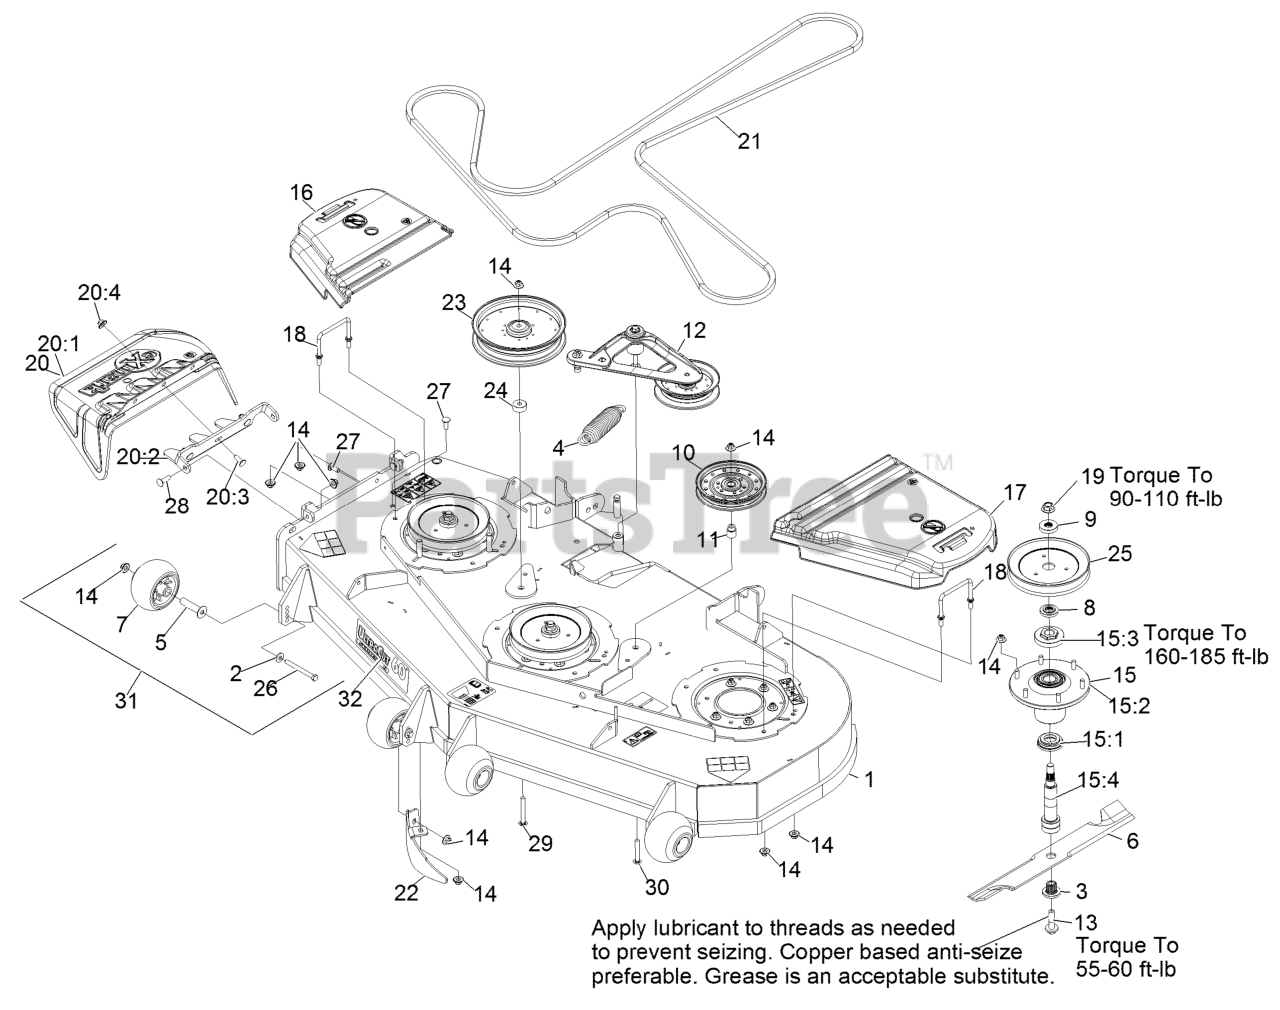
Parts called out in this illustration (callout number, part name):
1	DECK ASM,W/DECALS 60
2	WASHER-BELLEVILLE
3	BUSHING,SPLINED
4	SPRING-EXTENSION
5	AXLE, ROLLER
6	Blade-Extreme 2, 20.50"
7	ROLLER-SCALP, ANTI
8	SPACER,SPLINED STEPPED
9	SPACER,SPLINED
11	BUSHING-IDLER
12	DECK IDLER ASM
13	SCREW,SEMS 1/2-20 X 2.19
14	Nut-Nyloc 3/8-16 Flg
15	ASM,SPINDLE HOUSING
15:1	GUARD,BOTTOM
15:2	ASM,CUTTER HOUSING
15:3	NUT, SPINDLE 7/8-14
15:4	SPINDLE,DOUBLE SPLINE
16	COVER-BELT, RH
17	COVER-BELT, LH
18	WIREFORM-COVER
19	NUT-FLANGE, CENTERLOCK
20	ASM,DISCHARGE CHUTE
20:1	CHUTE,DISCHARGE
20:2	BRACKET,DISCHARGE CHUTE
20:3	SCREW-CARR
20:4	Nut-Nyloc 3/8-16 Flg
21	BELT,V-5V-198.75
22	DOGLEG - LZ60
23	PULLEY-IDLER
24	SPACER-IDLER
25	SHEAVE,BLADE DRIVE 7.25
26	SCREW-HH 3/8-16 X 3 3/4 GR 8
27	SCREW-CARR
28	Bolt-Carriage 3/8-16 X 1 1/4
29	SCREW-CARR
30	SCREW-CARR
31	KIT, ANTI-SCALP ROLLER
32	DECAL,ULTRACUT 60 SERIES
